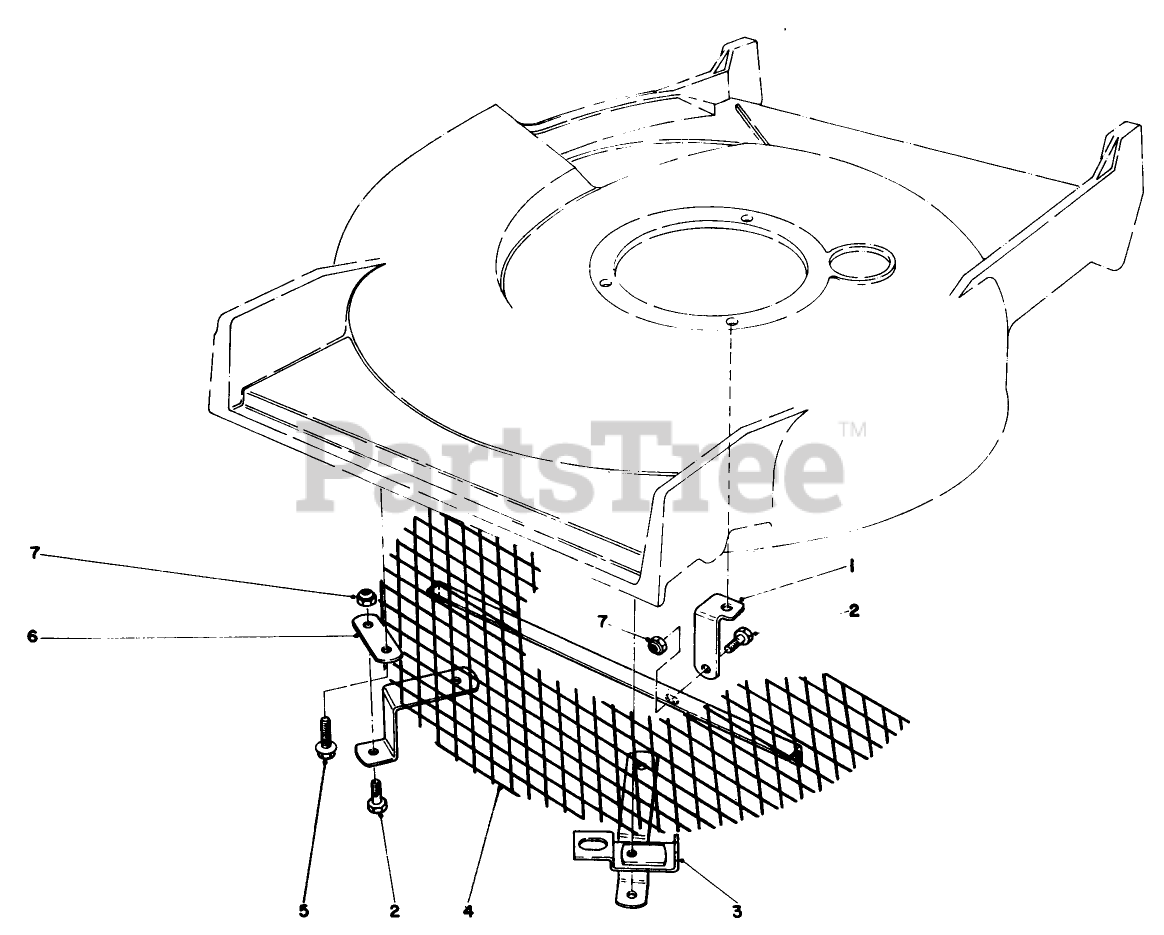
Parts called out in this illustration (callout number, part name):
2	SCREW-HH
3	MTG. BRACKET W.A.
5	SCREW-THD ROLL, HWH
7	NUT-LOCK, NI
